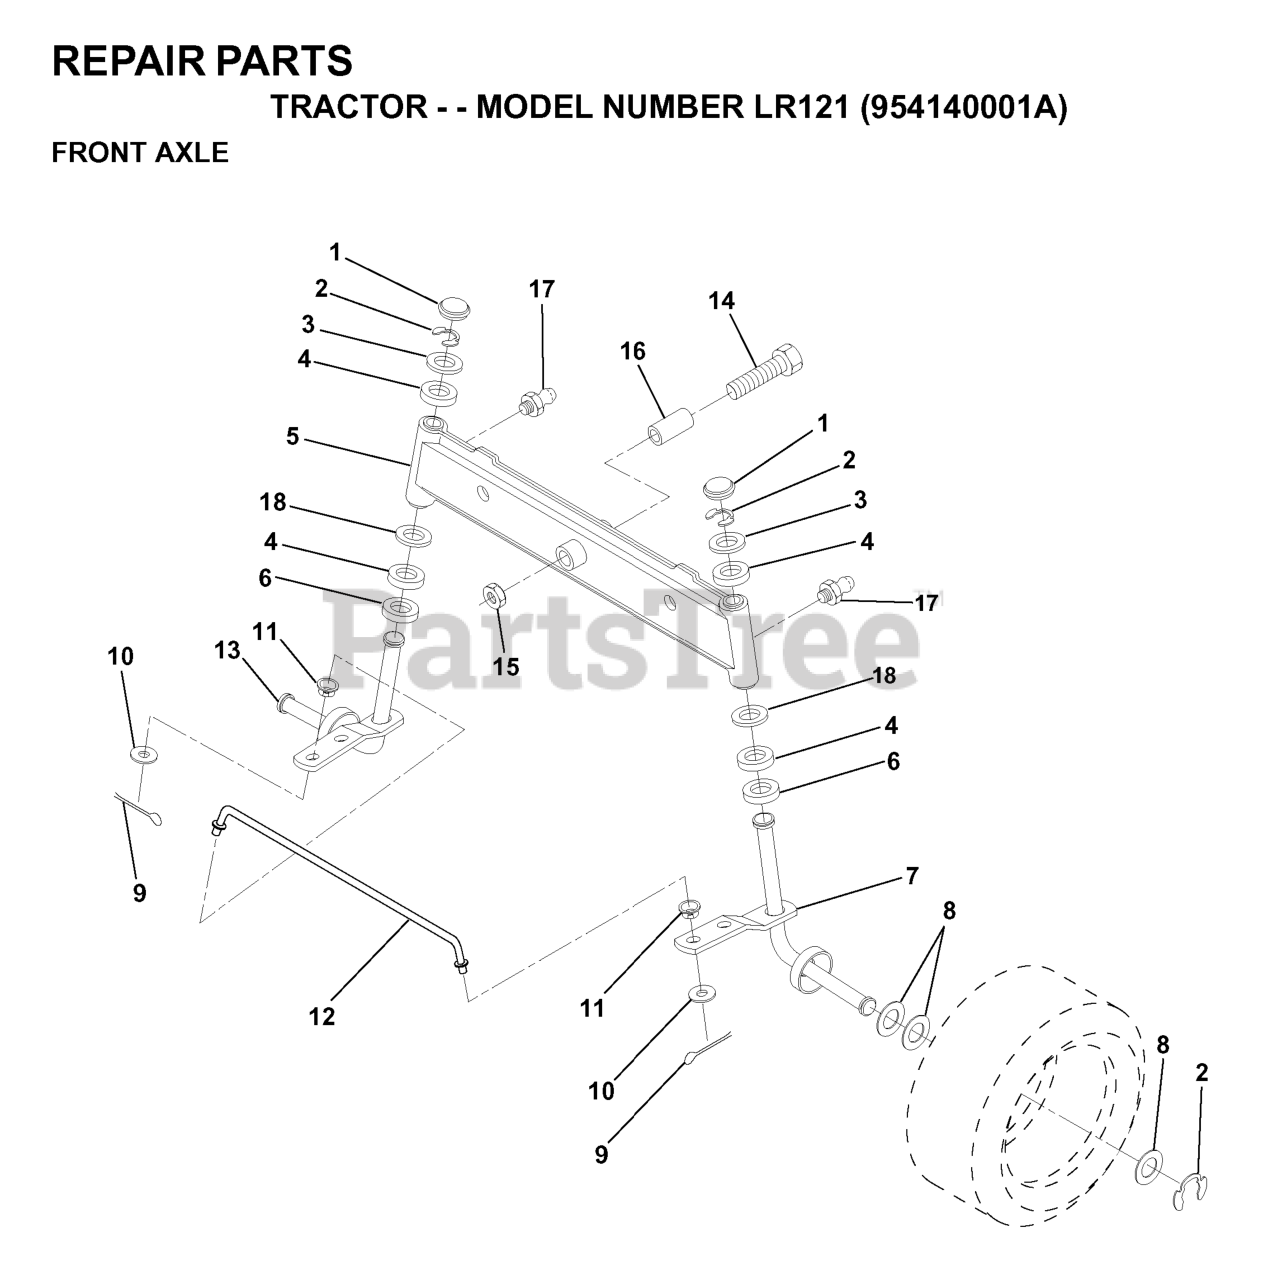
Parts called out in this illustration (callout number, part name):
1	CAP.SPINDLE.BLACK
4	BRNG T
6	THRUST WASHER
7	SPINDLE ASSY RH NLA
9	COTTER PIN
10	WASHER
11	BUSHING.DRAGLINK (2 2)
12	TIE ROD
13	SPINDLE ASSY LH
14	Bolt, Hex Head 5/8-11 x 3-1/2
15	NUT-LOC,FLANGE LT
16	BEARING
17	ZERK M
